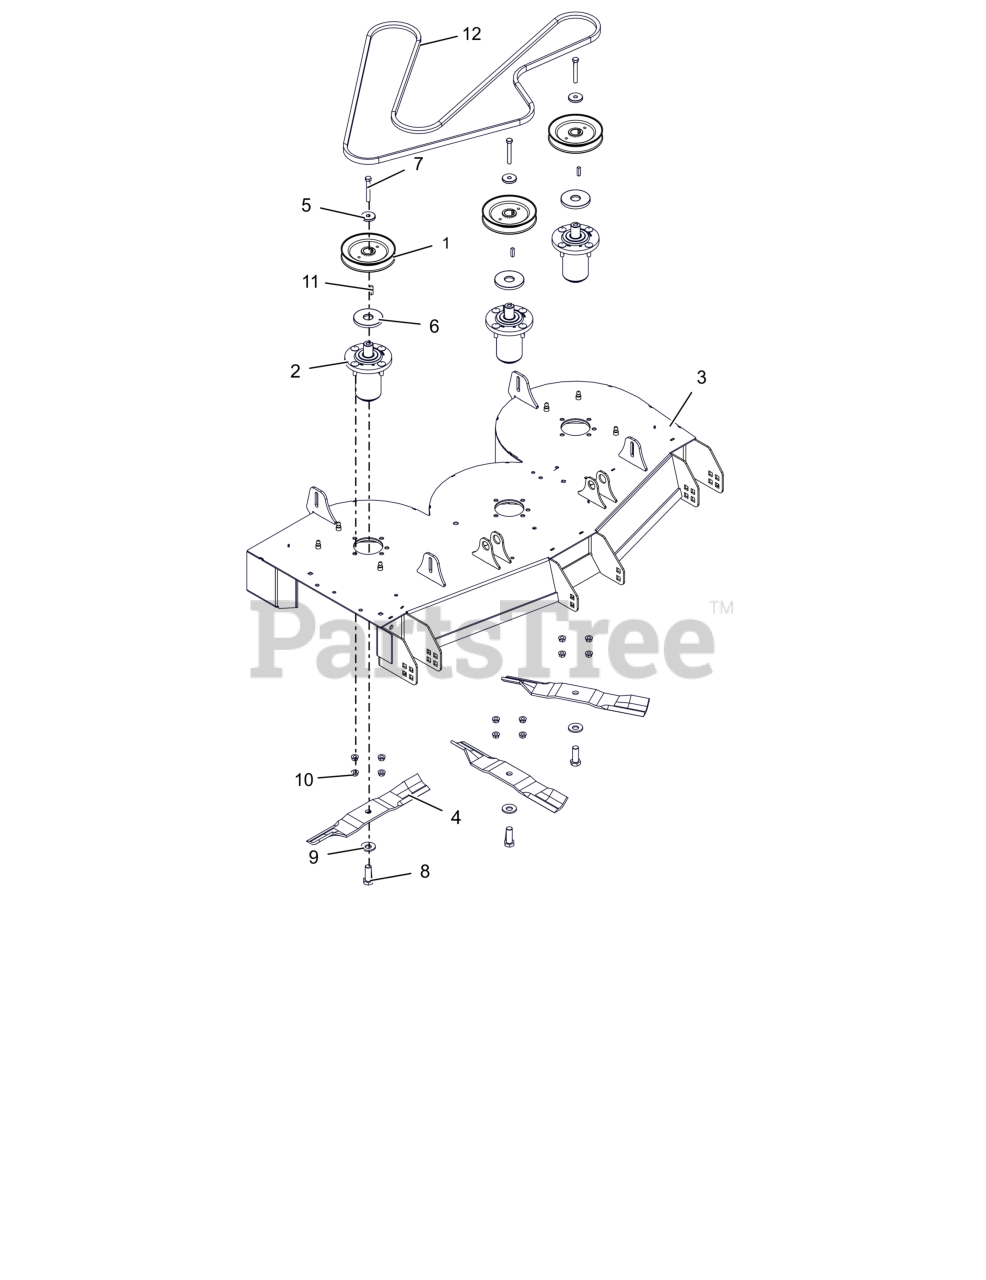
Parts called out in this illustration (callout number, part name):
1	PULLEY- V-1.000 ID X 5.750 OD
2	ASM, ALUM SPINDLE
3	WLDMT, DECK RIDGELINE 48 (ORANGE)
4	BLADE, 16.19" MOWER (HI-LIFT)
5	RETAINER, SHEAVE
6	SPCR- SHEAVE SPINDLE
7	BLT, HEX .38-16X2.75 G8 ZCC
8	BLT, HEX .62-18X1.75 G8 ZCC
9	WSHR-BLVL .669X1.535X.138
10	NUT-LK-CTR-FLG .375-16 GF ZCC
11	KEY, SQ .25X.25X1.00 RC 40-50
12	V-BELT, HB SECTION 123.230
